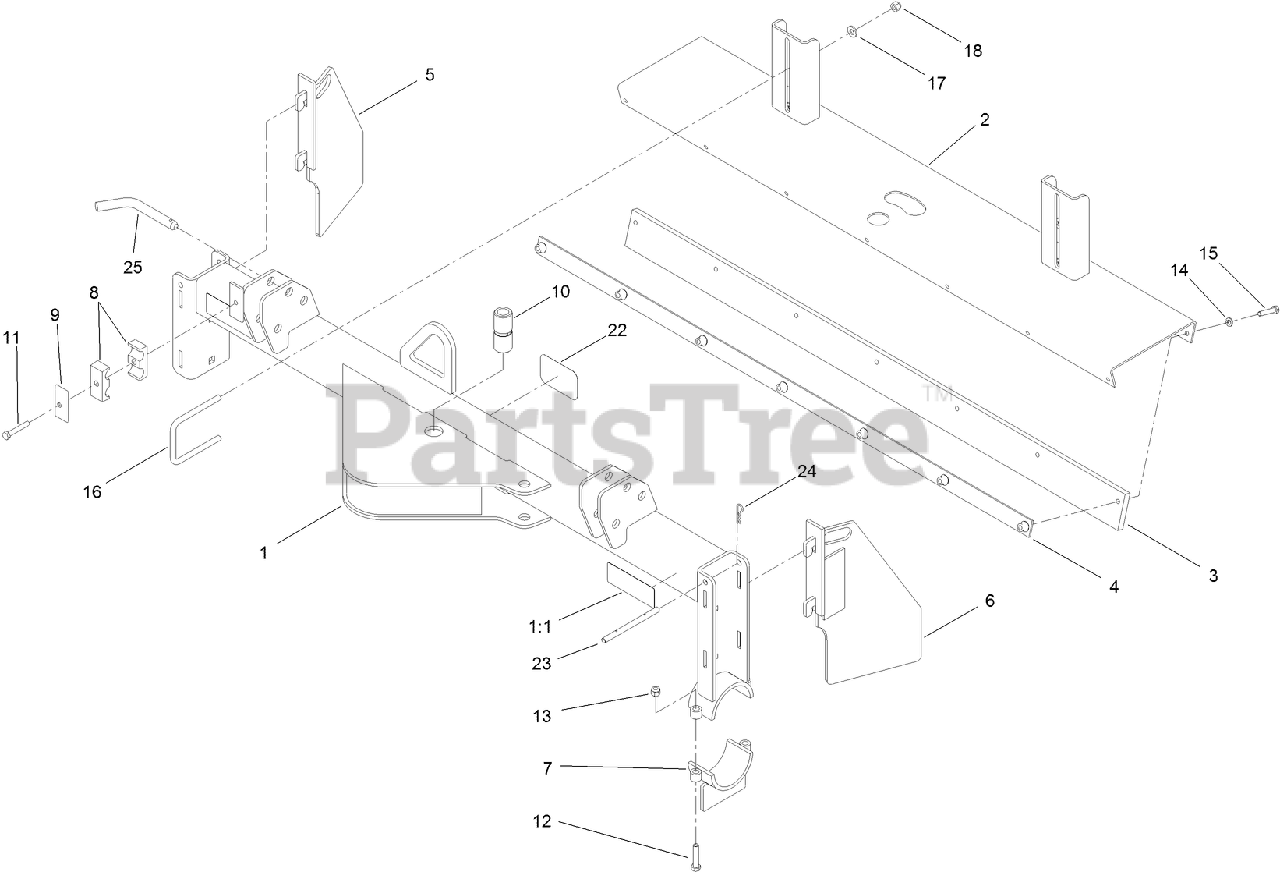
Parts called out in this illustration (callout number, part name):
1	FRAME-MAIN
1:1	DECAL-DANGER
2	MOUNT-BARRIER
3	BARRIER-RAKE
4	BARRIER-STRAP
5	BRACKET-GATE, LH
6	BRACKET-GATE, RH
7	CAP-LEG, FRAME
8	CLAMP-HOSE
9	PLATE-COVER
11	SCREW-HH
12	SCREW-HH
13	NUT-LOCK
14	WASHER-LOCK
15	SCREW-HH
16	U-BOLT
17	WASHER-HARDENED
18	NUT-LOCK, NI
22	DECAL
23	PIN-GATE
24	PIN-HAIR
25	PIN-HITCH
